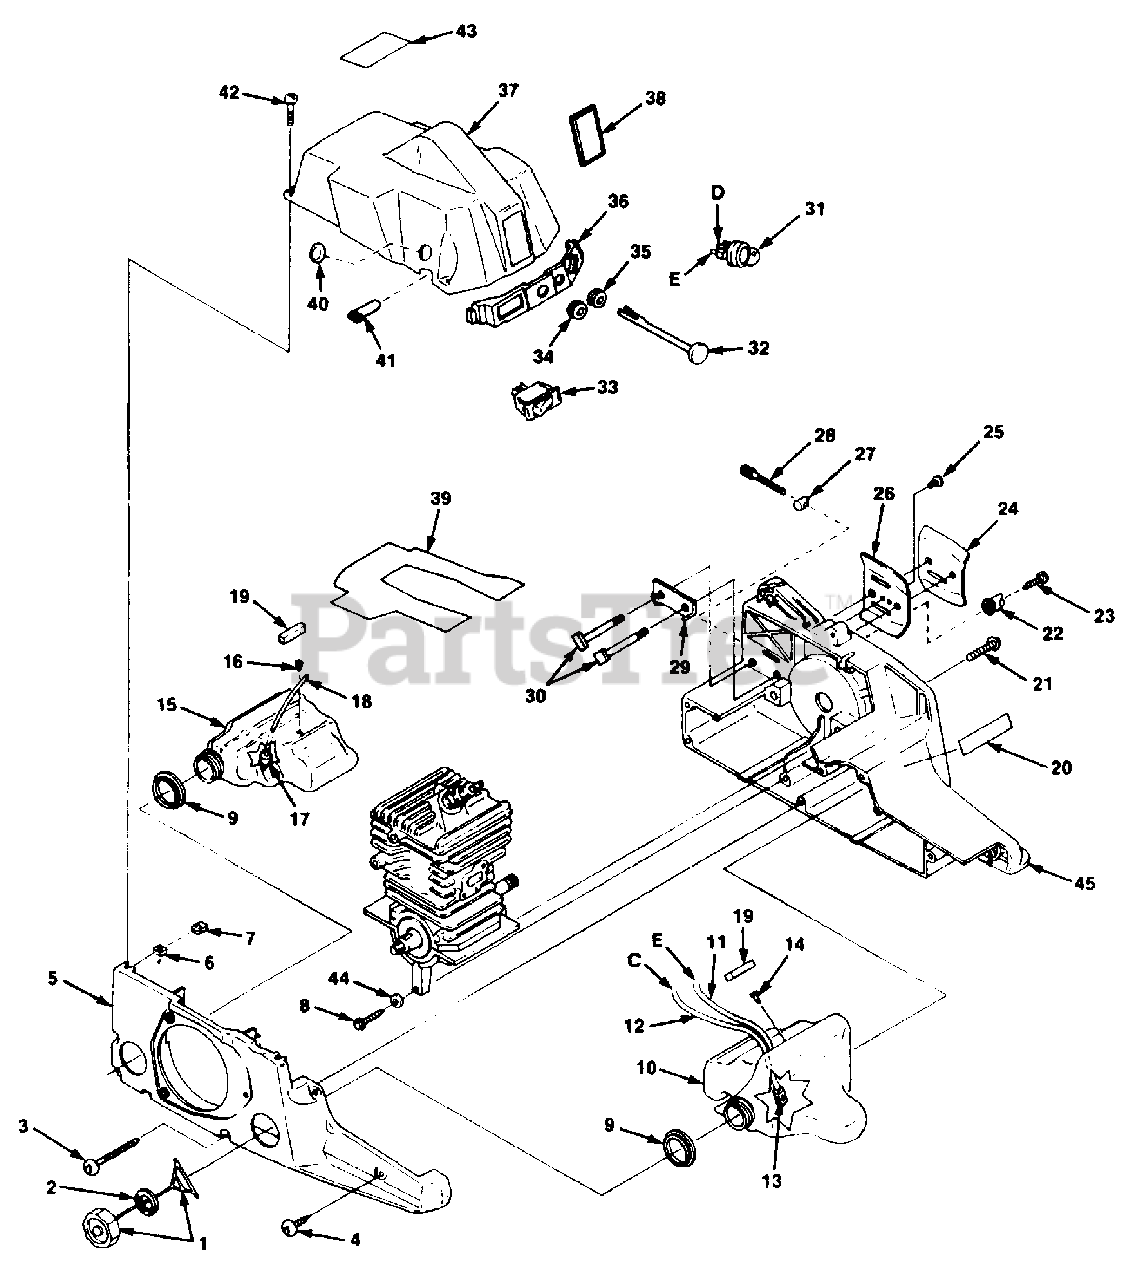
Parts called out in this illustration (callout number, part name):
1	CAP- Tank (w/retainer)
2	GASKET
4	SCREW- (8-16 x 5/8")
5	HOUSING- Starter side
6	NUT- Square (10-24)
7	NUT- Retainer
8	SCREW- Thd. forming
9	SEAL- Tank
10	TANK- Fuel
11	TUBING- Rubber (5 1/4")
12	TUBING- Rubber (9")
13	FILTER- Fuel
14	VALVE- Check
15	TANK- Oil
16	VALVE- Check
17	FILTER- Oil
18	TUBING- Rubber
19	FILTER- Valve
20	DECAL- Instruction
21	SCREW
22	STOP- Chain
24	PLATE- Guide bar (outer)
26	PLATE- Guide bar (inner)
27	PIN- Guide bar adjusting
28	SCREW- Guide bar adjusting
29	PLATE- Guide bar stud
30	BOLT- Guide bar
31	BULB- Primer bulb
32	ROD- Choke
33	SWITCH
34	BOOT- Throttle rod
35	GROMMET
36	PANEL- Control
37	COVER- Cylinder
38	SCREEN- Air inlet
39	FOAM- Adhesive
40	PLUG- Idle speed
41	GROMMET- Hi/Lo
42	SCREW- Rd. hd.
43	LABEL- Warning
44	WASHER- Lock
45	HOUSING- Drive side
